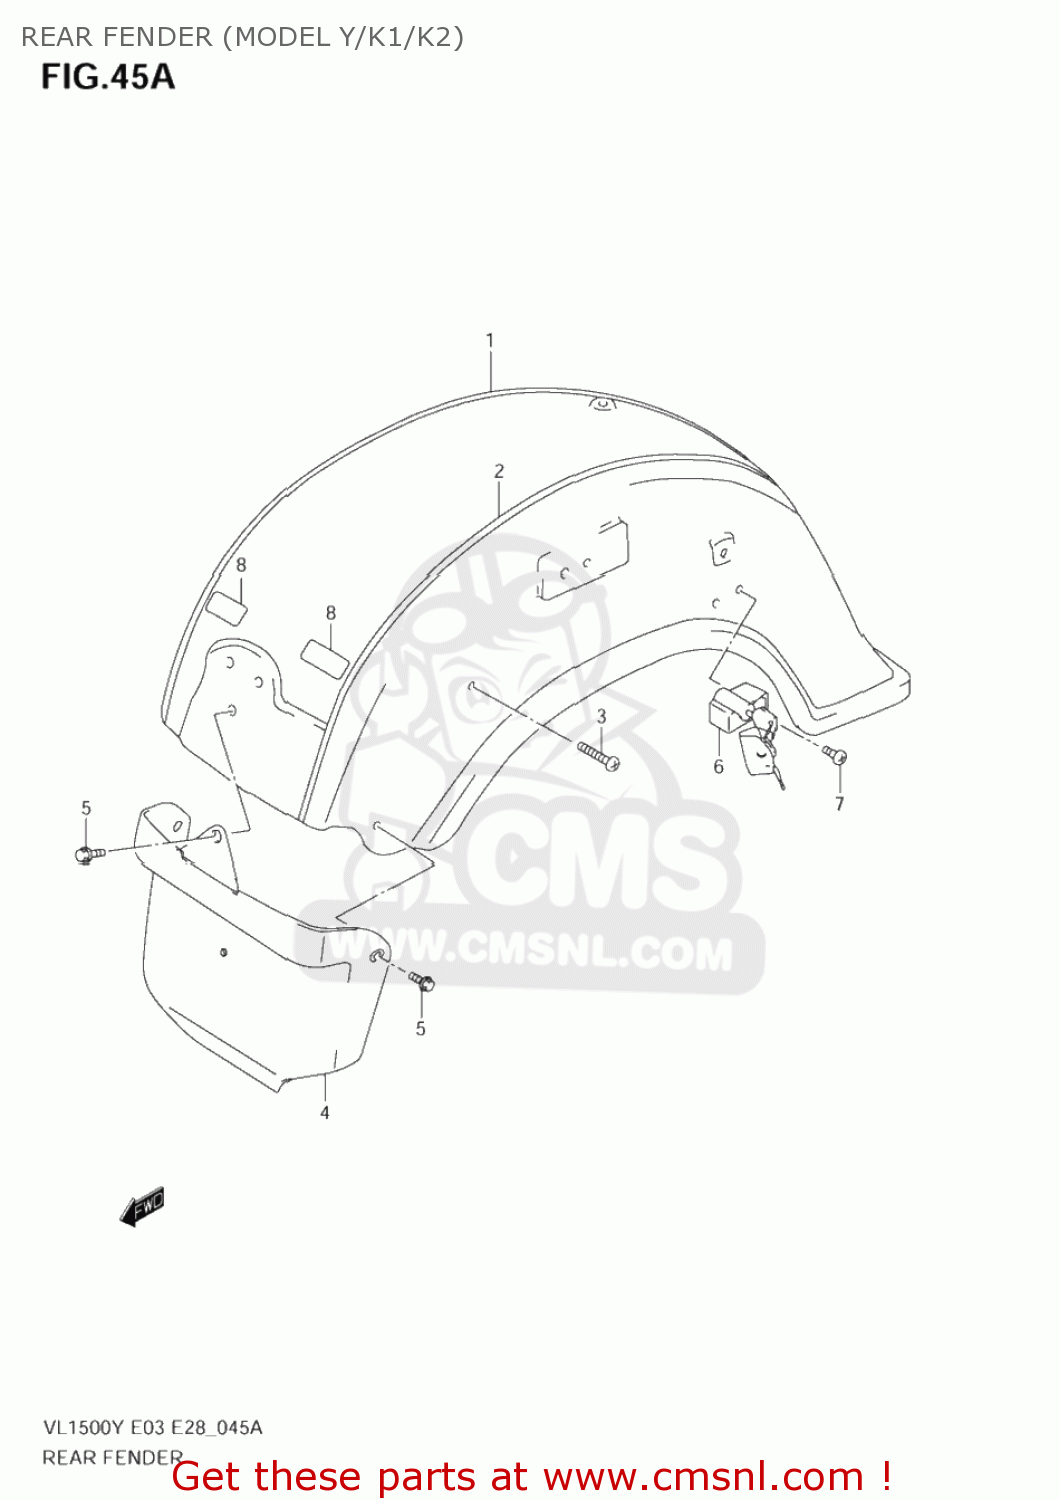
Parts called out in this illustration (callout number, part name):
1	FENDER,RR
2	TAPE SET,RR FENDER
3	BOLT(8X37)
4	MUDGUARD,RR FENDER FR
5	BOLT(6X16)
6	LOCK SET,HELMET
7	SCREW(6X14)
8	TAPE,RR FENDER
